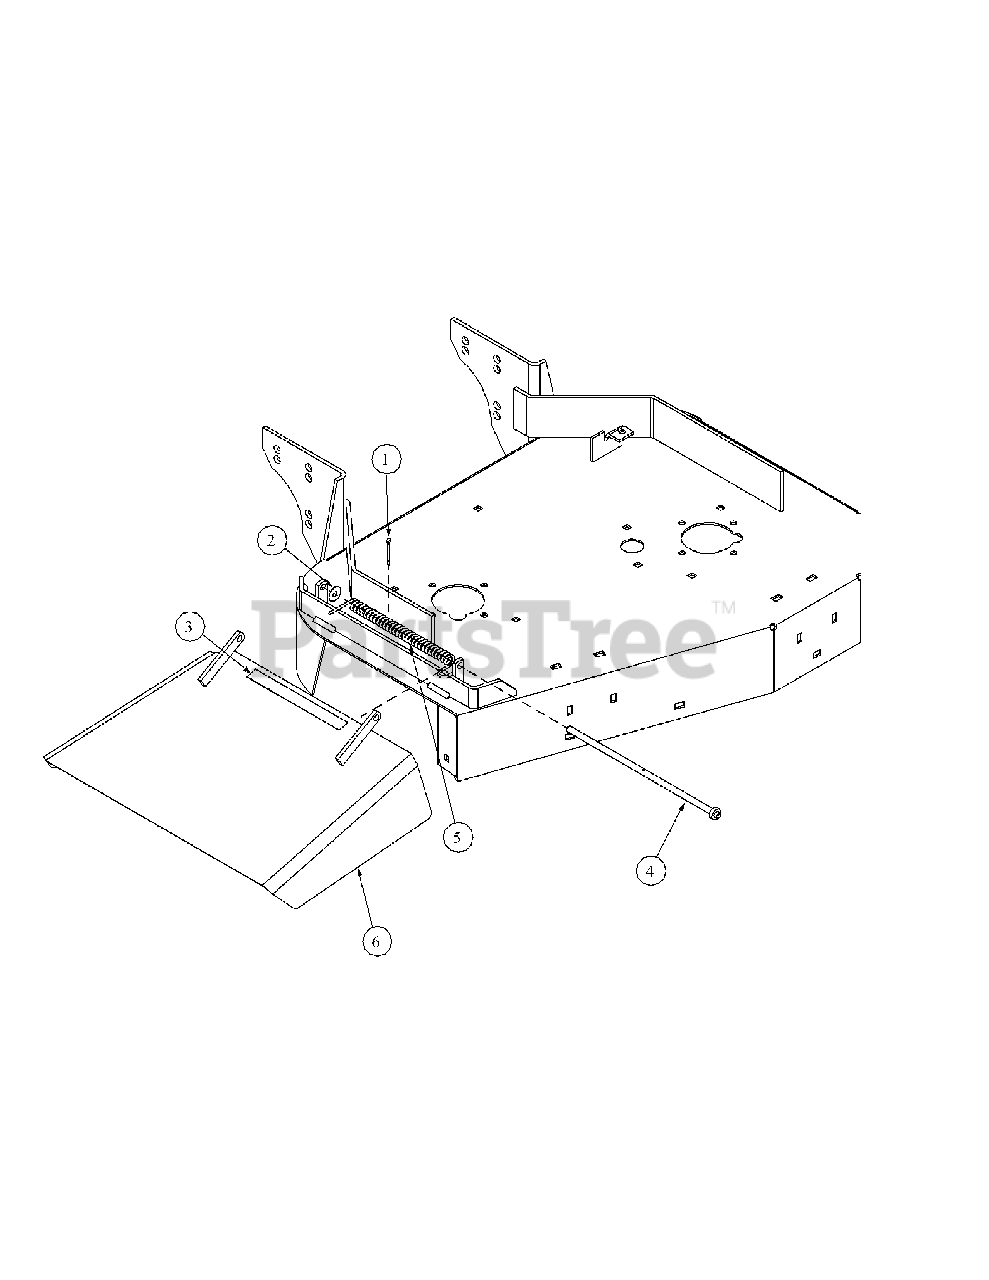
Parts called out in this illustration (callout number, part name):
1	Cotter Pin, 5/32 x 1 1/2 Zinc
2	Flat Washer, 3/8, Zinc
3	Decal, Cut Line
4	Pin, Deflector Assembly
5	Torsion Spring
6	Chute Assembly Discharge
